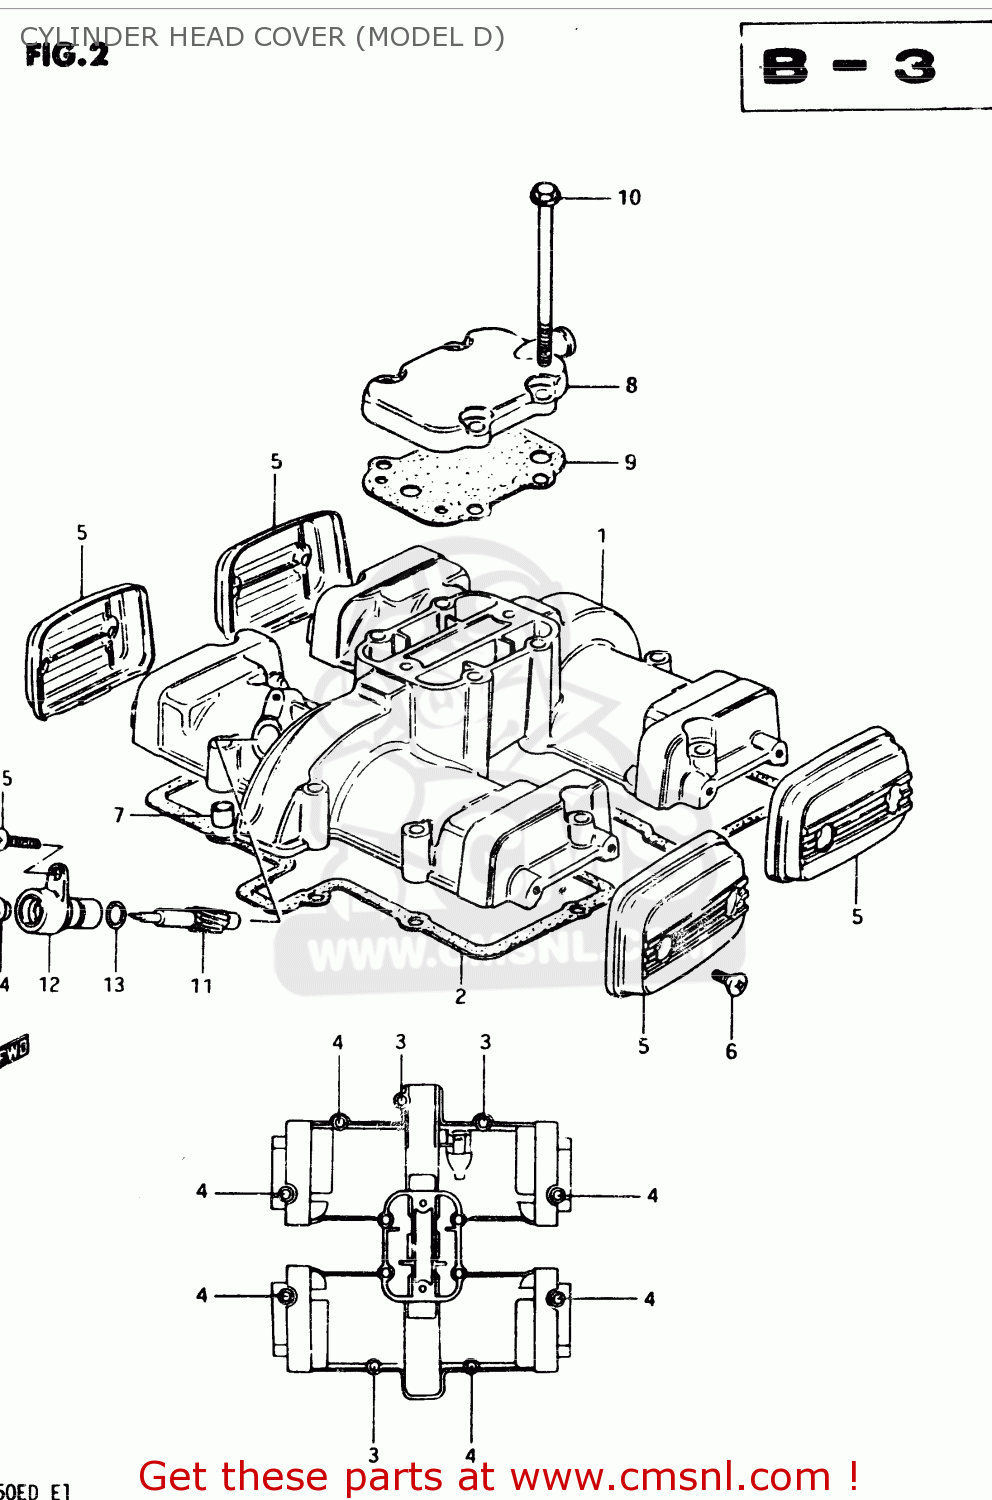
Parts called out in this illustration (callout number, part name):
1	COVER,CYLINDER HEAD
2	GASKET,CYLINDER HEAD COVER (MCA)
3	BOLT (6X40)
4	BOLT
5	CAP,CYLINDER HEAD COVER
6	SCREW(5X12)
7	PIN(6.2X8X11)
8	COVER,BREATHER
9	GASKET,BREATHER COVER (MCA)
10	BOLT (6X75)
11	GEAR,TACHOMETER DRIVEN
12	SLEEVE,TACHOMETER DRIVE GEAR
13	SEAL,TACHOMETER DRIVEN
14	SEAL,OIL(5X12X8)
15	SCREW(5X12)
